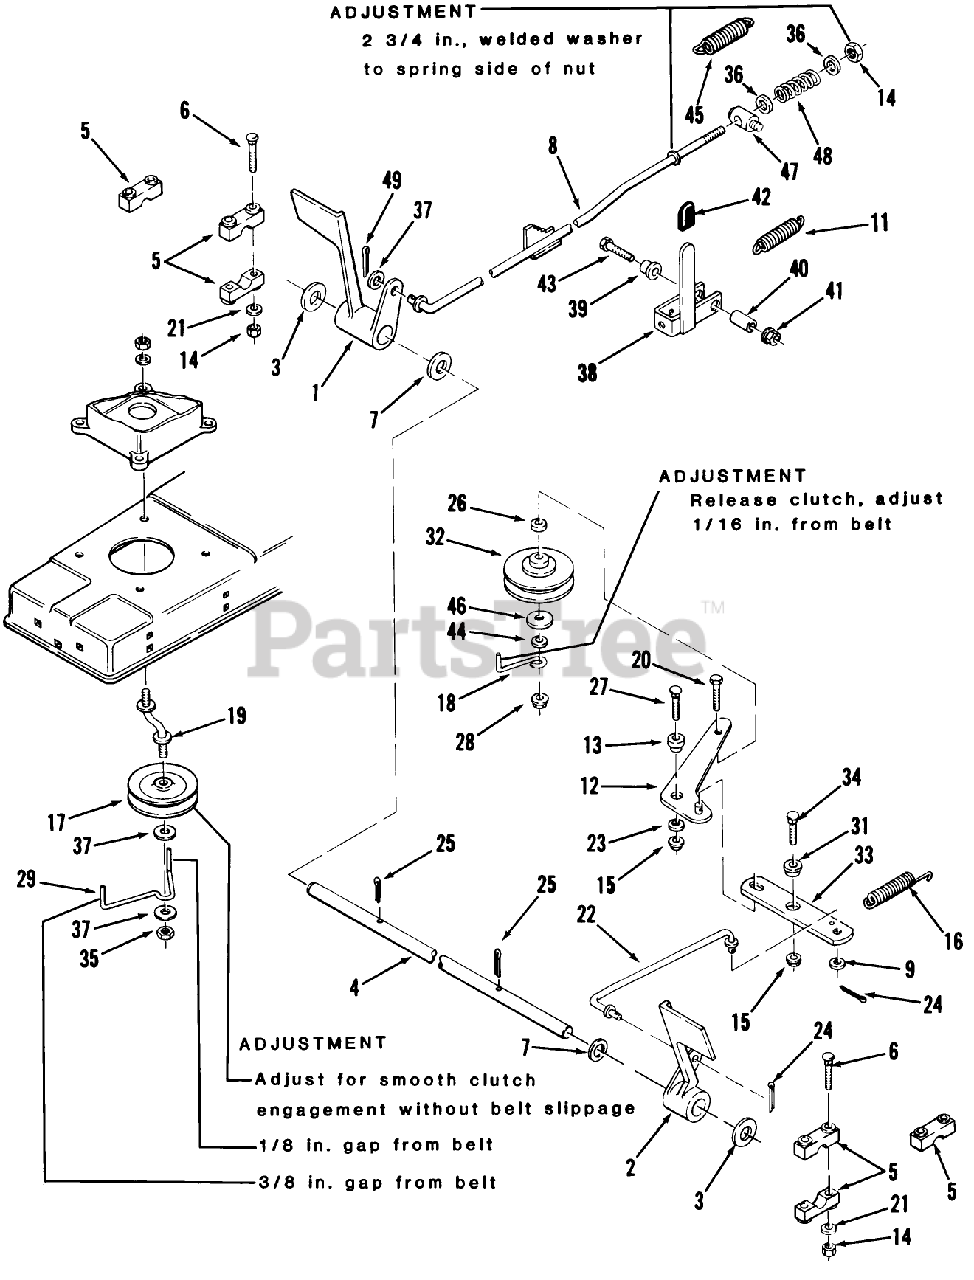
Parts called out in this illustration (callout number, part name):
1	PEDAL-BRAKE *R
3	Special Washer
9	WASHER 5/16 SAE
11	SPRING-EXTENSION
13	SPACER-IDLER ARM
16	SPRING
17	PULLEY-IDLER STATION
21	WASHER 5/16 SAE
22	ROD-CLUTCH *R
32	Pully-Idler
38	PAWL-HANDLE ASSY
39	SPACER
40	SPACER
42	GRIP
45	SPRING-EXTENSION
46	WASHER
47	TRUNNION-LIFT
